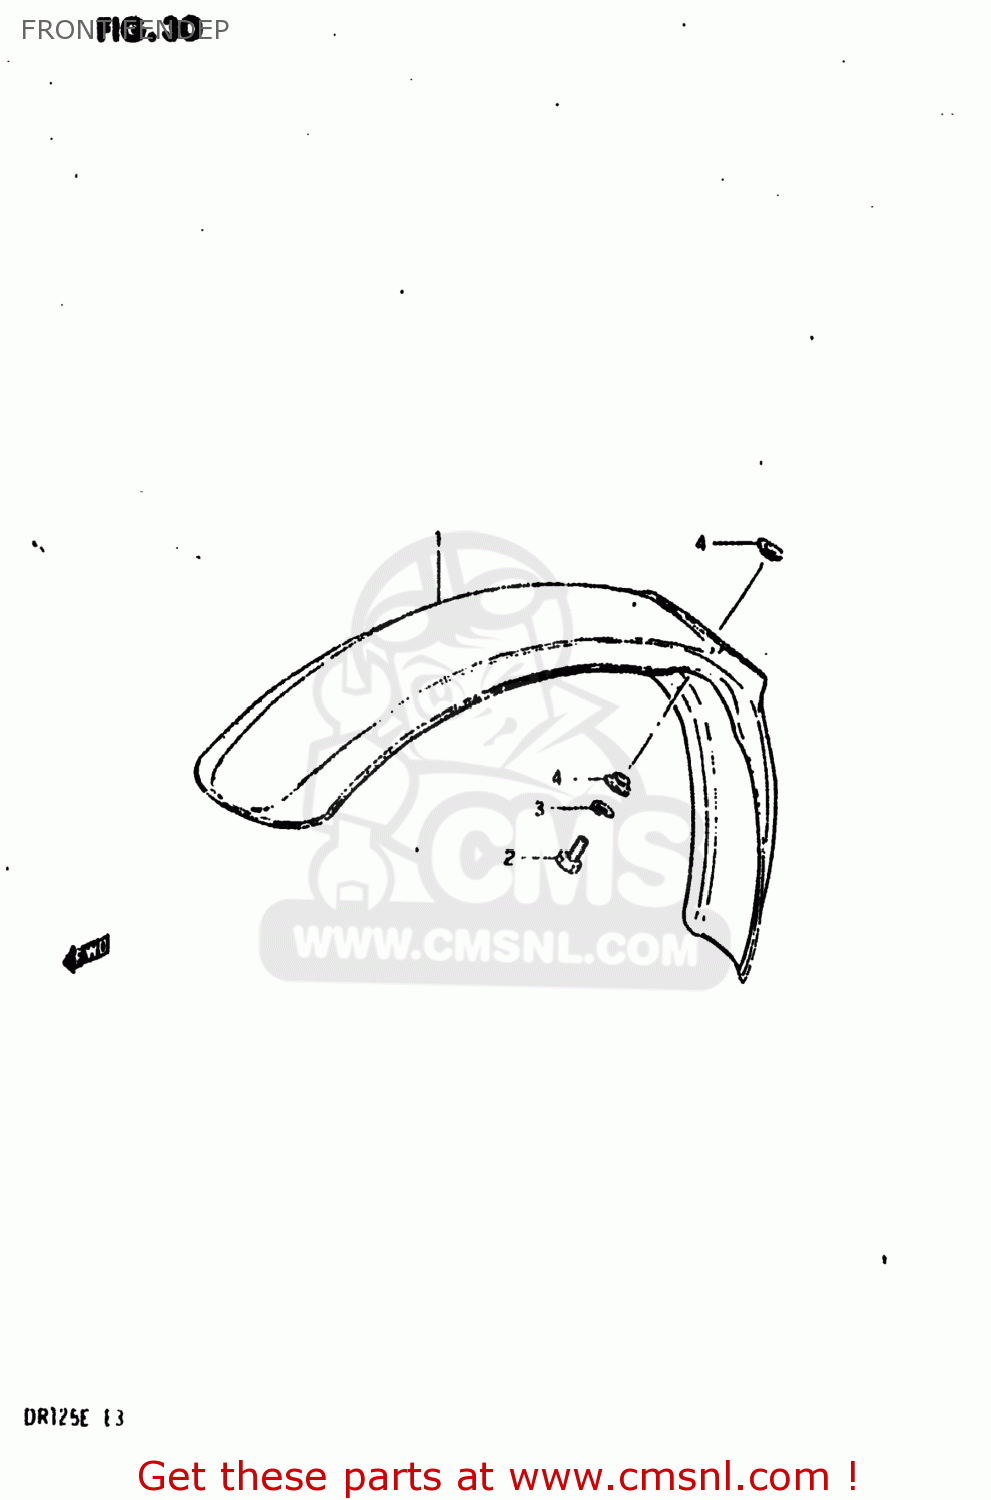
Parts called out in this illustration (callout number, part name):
1	FENDER,FRONT
2	BOLT, UPPER
3	LOCK WASHER
4	SPACER
